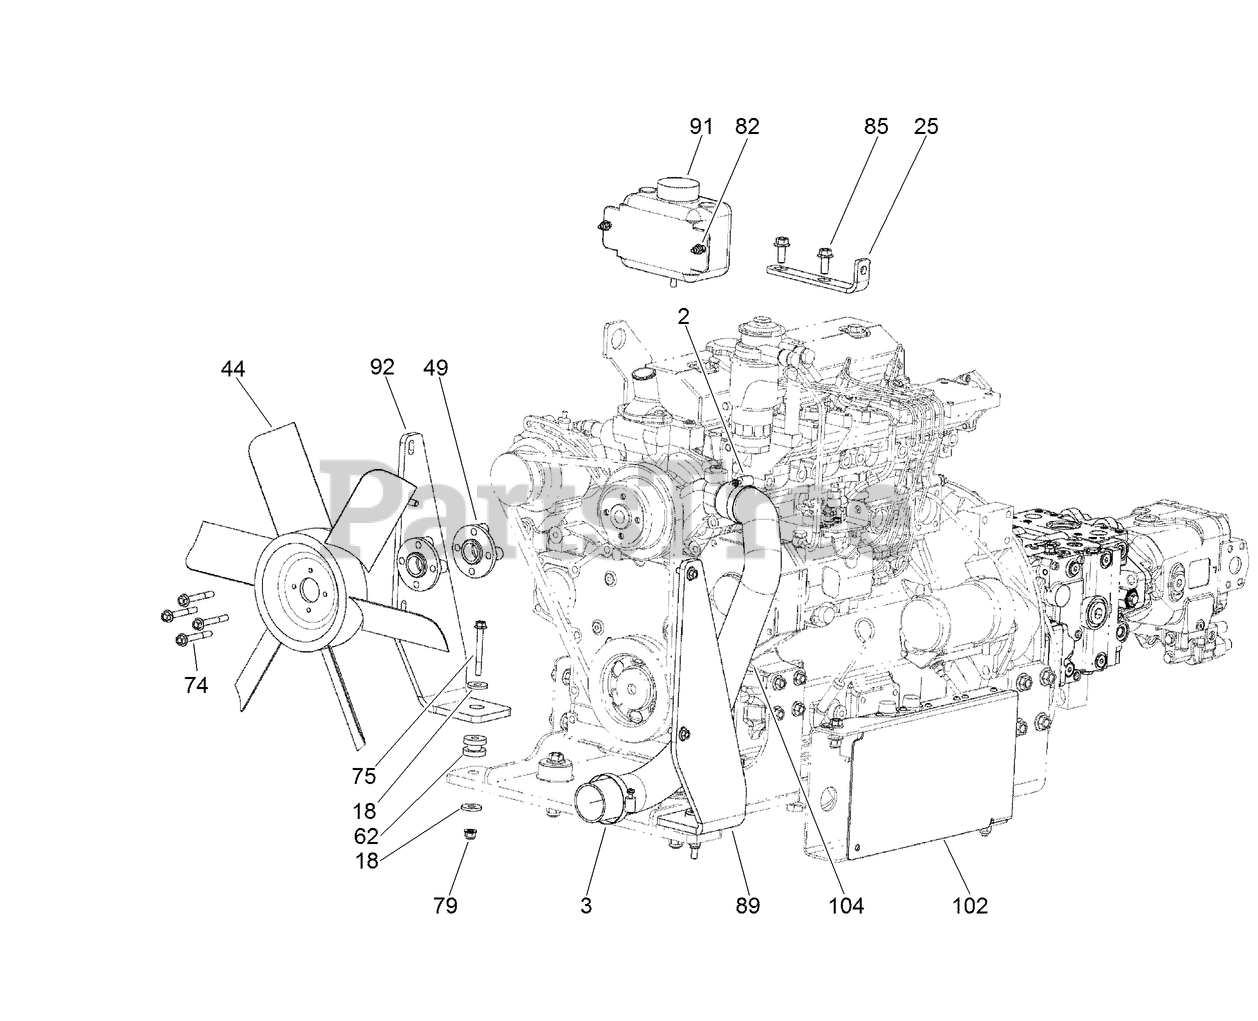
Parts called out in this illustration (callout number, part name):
2	CLAMP-Hose Type F #32
3	CLAMP - Hose Type F # 36
25	PLATE - Radiator Strap Mount
49	SPACER - Fan Hub
62	MOUNT - Isolator
74	SCREW-FLANGE
75	SCREW-FLANGE
79	NUT-TORQUE, PREVAILING
82	SCREW, METRIC FLANGE w/BODY-M6 x 25
85	SCREW-FLANGE
89	BRACKET - Radiator Mounting
91	TANK-Overflow
92	BRACKET - Radiator Mounting
102	COVER - Electrical
104	HOSE - Lower Radiator, Molded
